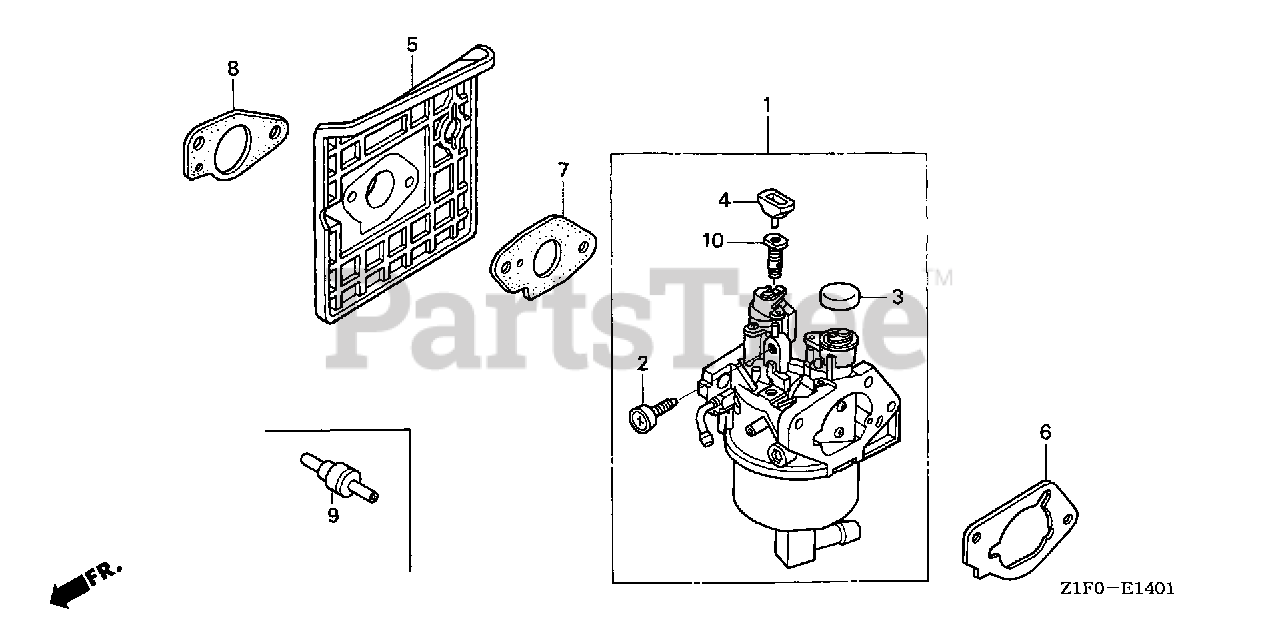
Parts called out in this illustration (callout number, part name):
1	CARBURETOR ASSY. (BEL6A D)
2	SCREW, THROTTLE STOP
3	CAP, CHOKE LEVER DUST
4	COLLAR, SET
5	INSULATOR, CARBURETOR
6	SPACER, CARBURETOR
7	GASKET, CARBURETOR
8	GASKET, INSULATOR
9	VALVE, DASHPOT CHECK
10	JET SET, PILOT (#45)
